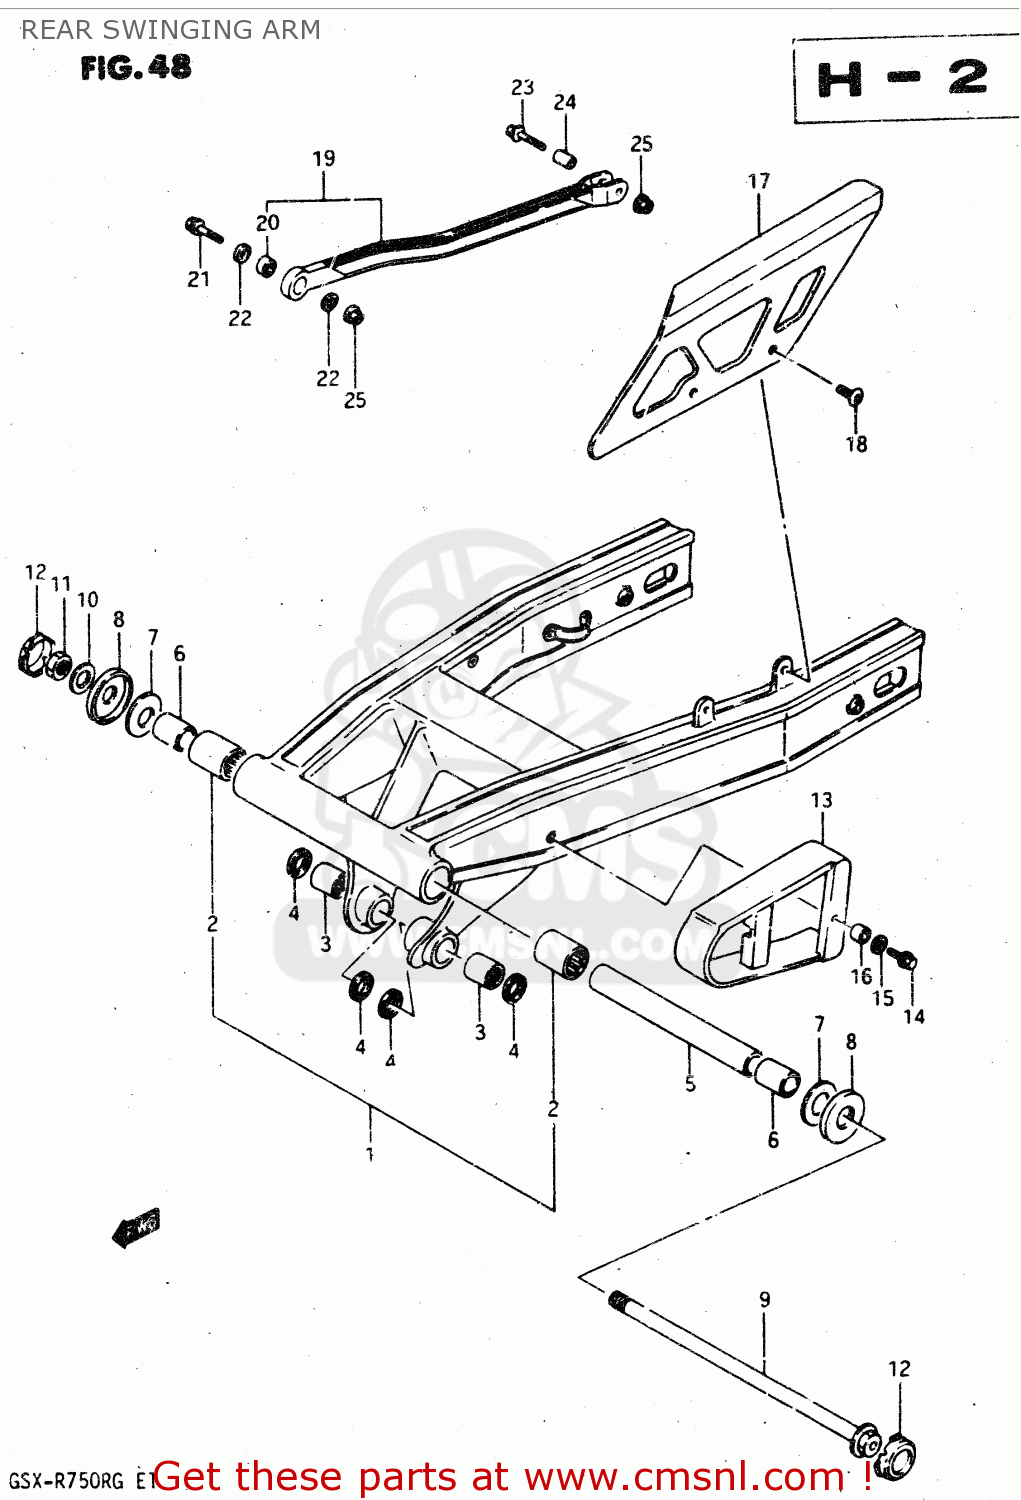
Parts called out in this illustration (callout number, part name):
1	SWING ARM ASSEMBLY,REAR
2	BEARING
3	ROLLER BEARING (17X24X25))
4	SPACER,REAR CUSHION ROD
5	SPACER,RR SWGARM PIVOT CTR
6	SPACER,RR SWGARM PIVOT BEARING
7	WASHER
8	COVER,RR SWGARM DUST SEAL
9	SHAFT,REAR SWING ARM
10	WASHER(14X27X3)
11	NUT
12	CAP,SWINGINGARM PIVOT
13	BUFFER,CHAIN TOUCH DEFENSE
14	BOLT,M6X1X20
15	WASHER(6.5X16X1.2)
16	SPACER(6.5X8.5X5.8)
17	CASE,CHAIN
18	SCREW(6X12)
19	TORQUE LINK SET,REAR
20	SPHERICAL BEARING,TORQUE
21	BOLT(8X38)
22	23
23	BOLT(8X35)
24	SPACER,RR TORQUE LINK RR
25	NUT
